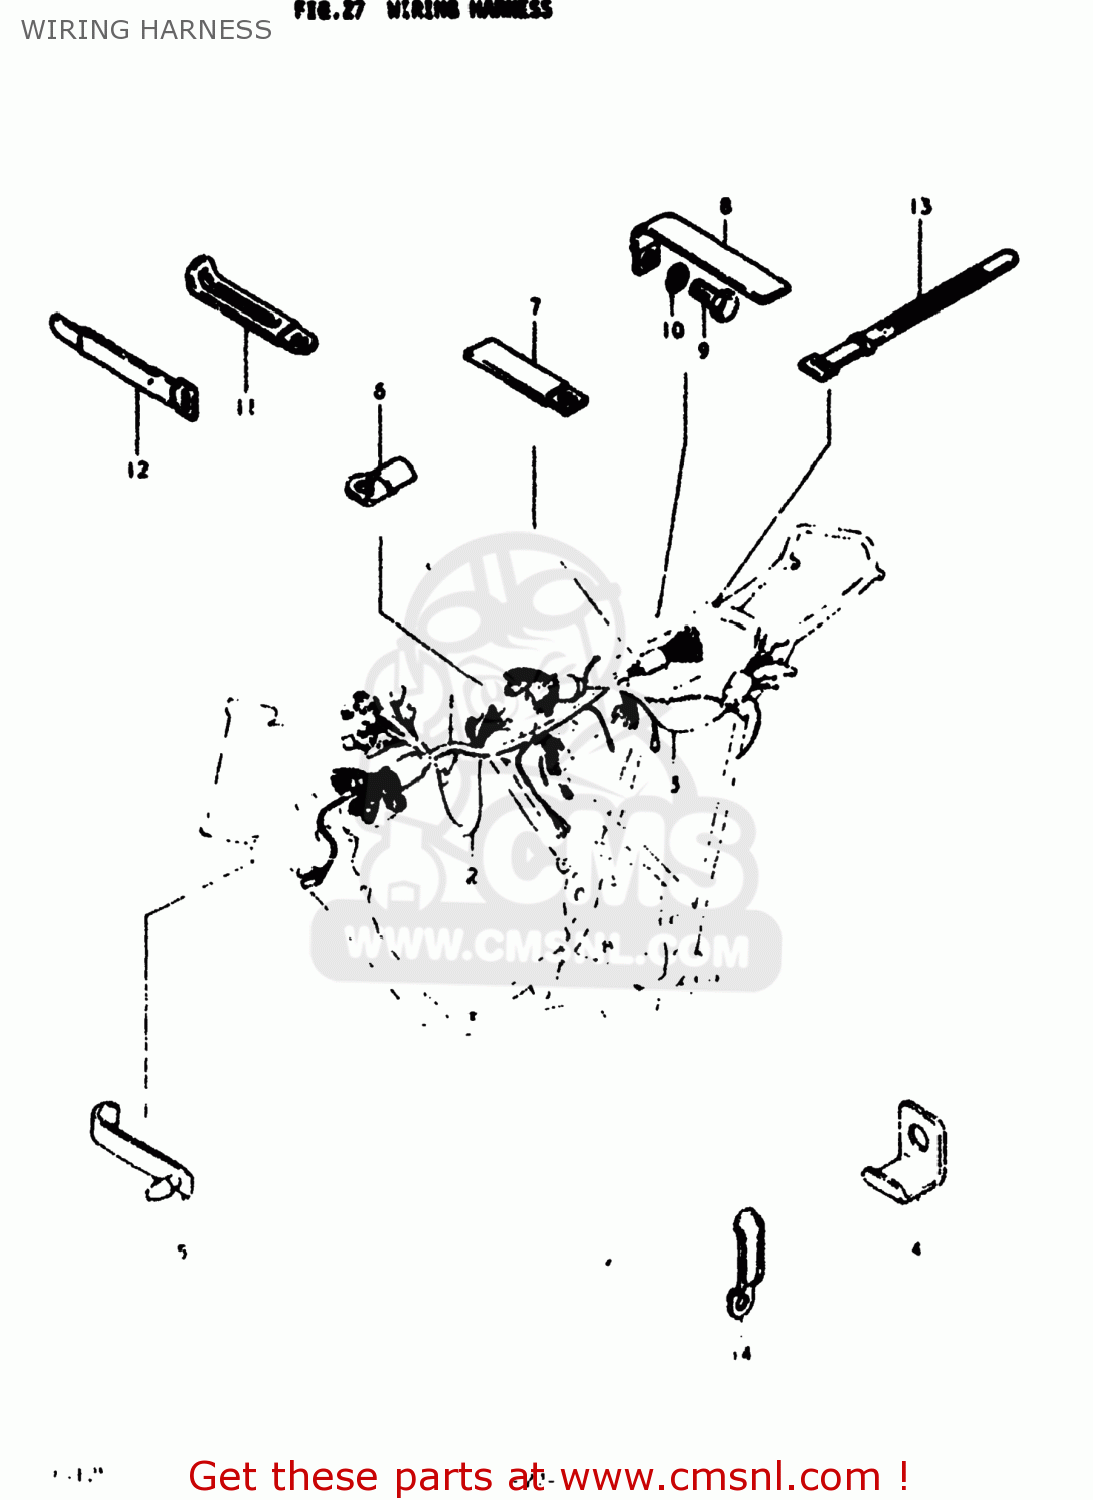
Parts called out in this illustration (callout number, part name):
1	HARNESS,WIRING
2	HARNESS,WIRING
3	HARNESS,WIRING NO.2
5	BAND
6	CLAMP
7	CLAMP
8	CLAMP
9	BOLT
10	LOCK WASHER
11	CLAMP
12	CLAMP
13	CLAMP
14	CLAMP
